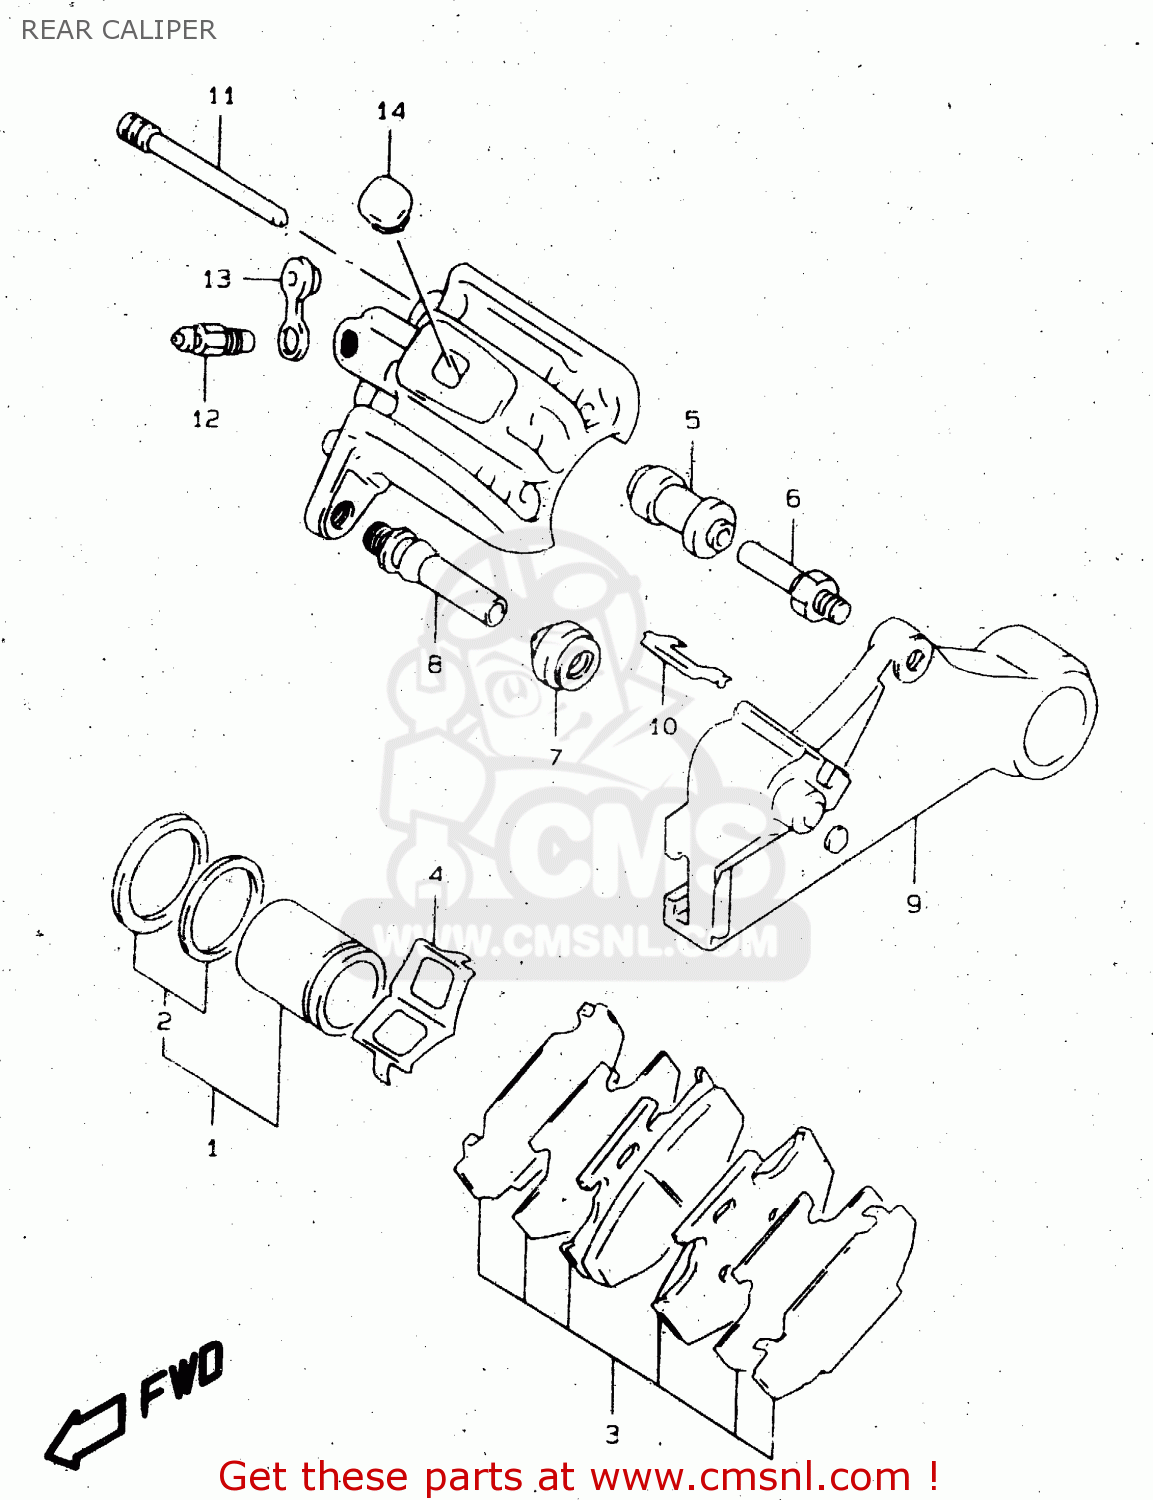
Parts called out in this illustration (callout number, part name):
1	PISTON SET
2	SEAL SET,PISTON
3	PAD & SHIM SET (NAS)
4	SPRING,PAD
5	BOOT
6	BOLT
7	BOOT
8	PIN
9	BRACKET
10	RETAINER,BRACKET
11	PIN,HANGER
12	BLEEDER
13	CAP,BLEEDER
14	COVER,RR CALIPER BODY
